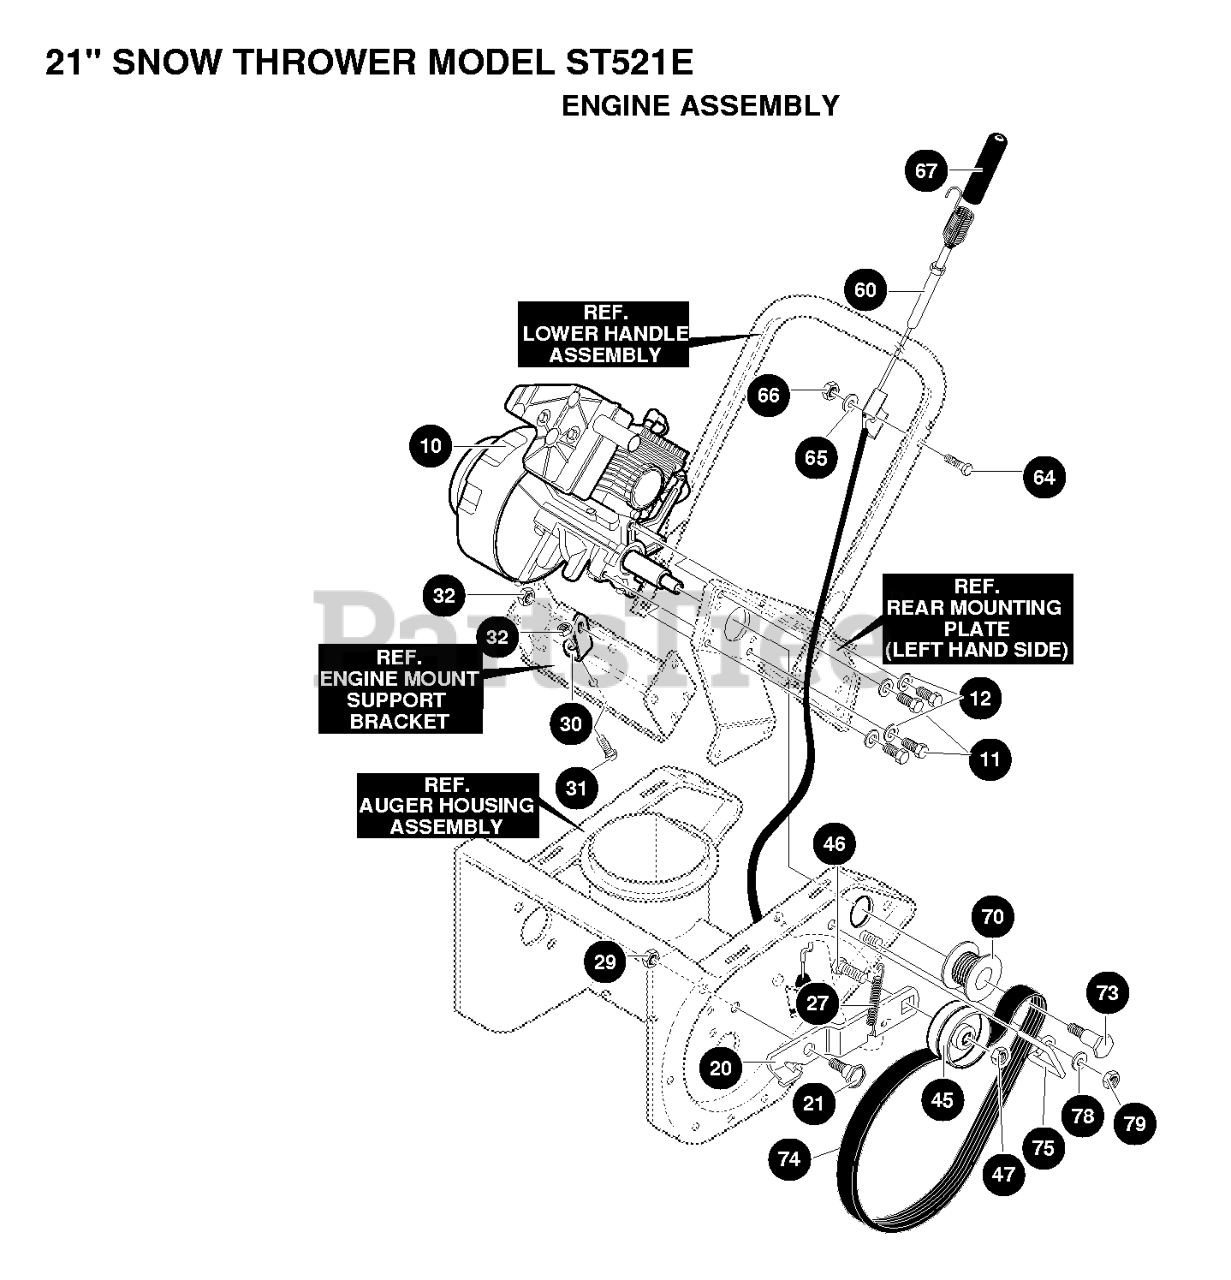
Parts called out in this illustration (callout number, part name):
10	See Engine Manual
11	SCREW, 5/16-18X .75 HHC
12	WASHER, HVSPTLK .328X.60X
20	BRACKET, IDLER ARM
21	BOLT, IDLER ARM
27	SPRING, TORSION, BRAKE
29	NUT, 5/16-18 REGHEXCTRLK
30	SUPPORT, ENGINE
31	SCREW 5/16-18X.50
32	NUT, 5/16-18 REGHEXCTRLK
45	PULLEY, IDLER 1.88 X .5 X .38
46	BOLT, 3/8-16X1.25 SPCARR
60	CABLE, DRIVE CONTROL
64	SCREW, 1/4-20 X 1.50 HHC
65	WASHER, FLAT .281X .63X.
67	COVER, CABLE SPRING
70	PULLEY HALF, 3L 2.00
73	BOLT, SHOULDER
74	BELT, 10 RIB POLY
75	GUIDE, BELT
78	WASHER, FLAT .406X .81X.
79	NUT, 5/16-18 REGHEXCTRLK
